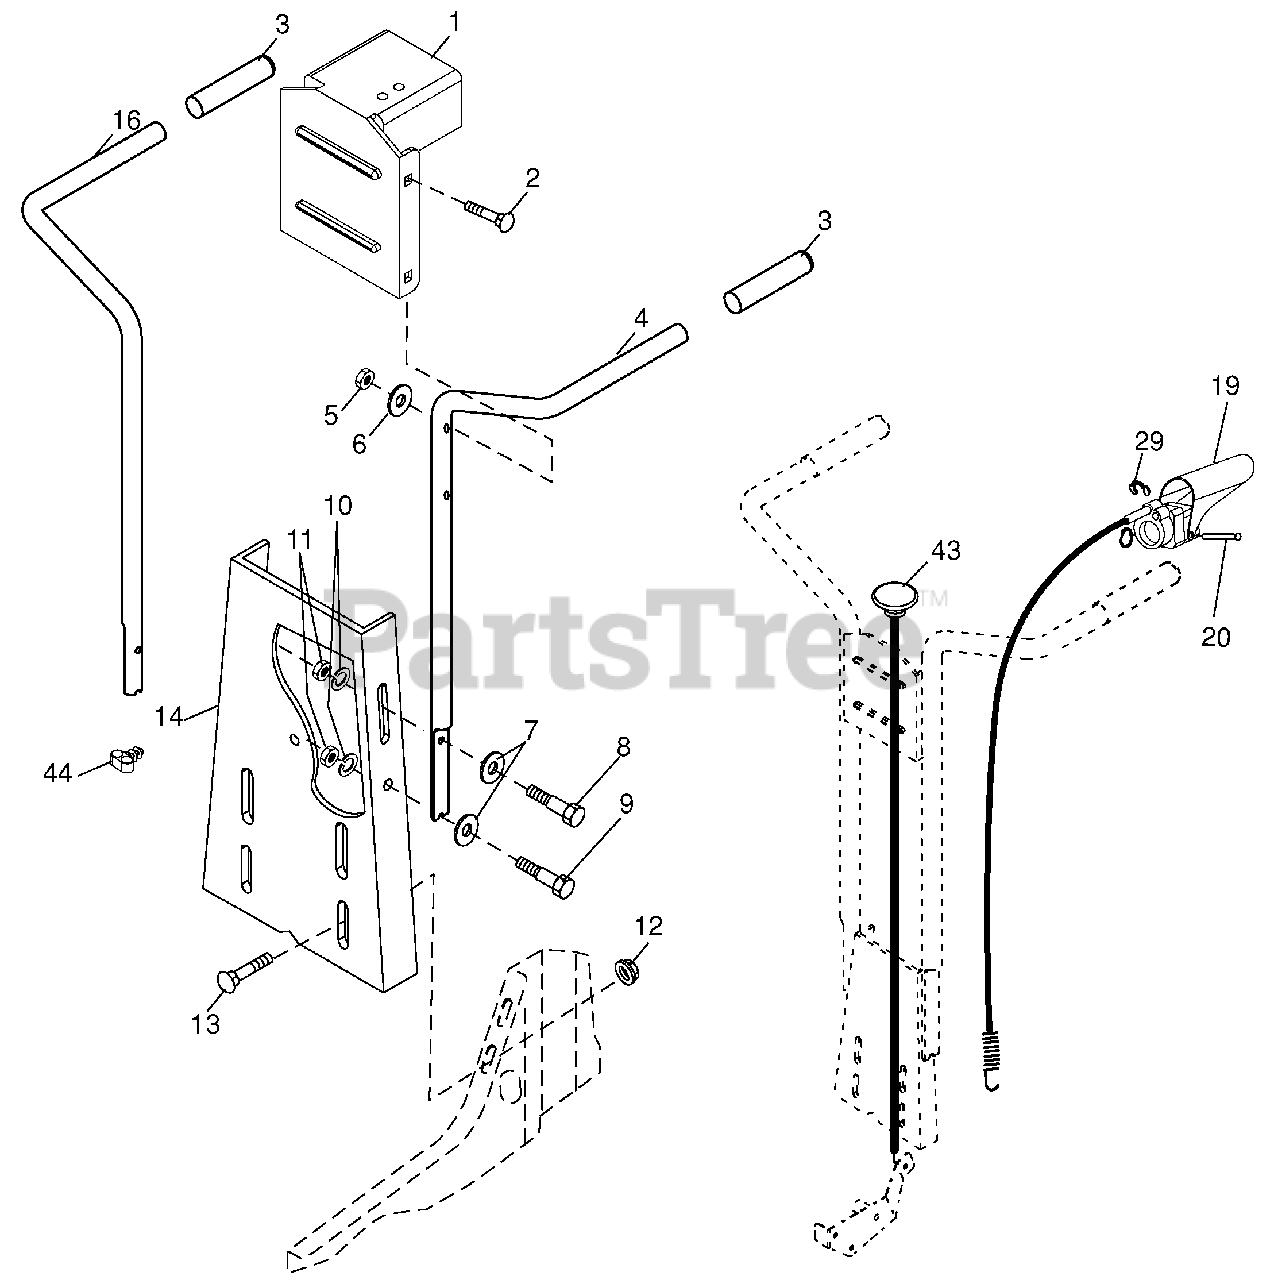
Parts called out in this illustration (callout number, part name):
1	Bracket, Handle
2	Bolt, Carriage 5/16-18 x 1-1/2
3	Grip, Handle
4	Handle, L.H.
5	Nut, Hex, Crownlock 5/16-18
6	Washer 11/32 x 11/16 x 16 Gauge
7	Washer 3/8 x 7/8 x 14 Gauge
8	Bolt, Hex Head 5/16-18 x 1-1/4
9	Bolt, Hex Head 5/16-18 x 1
10	Washer, Lock 5/16
11	Nut, Hex 5/16-18
12	Nut, Hex, Flanged 5/16-18
13	Bolt, Carriage, Gr. 5 5/16-18 x 3/4
14	Panel, Handle
16	Handle, R.H.
19	Tine Control Lever Assembly
20	Pin, Pivot
29	Retaining Ring
43	Cable Assembly, Reverse
44	Clip
